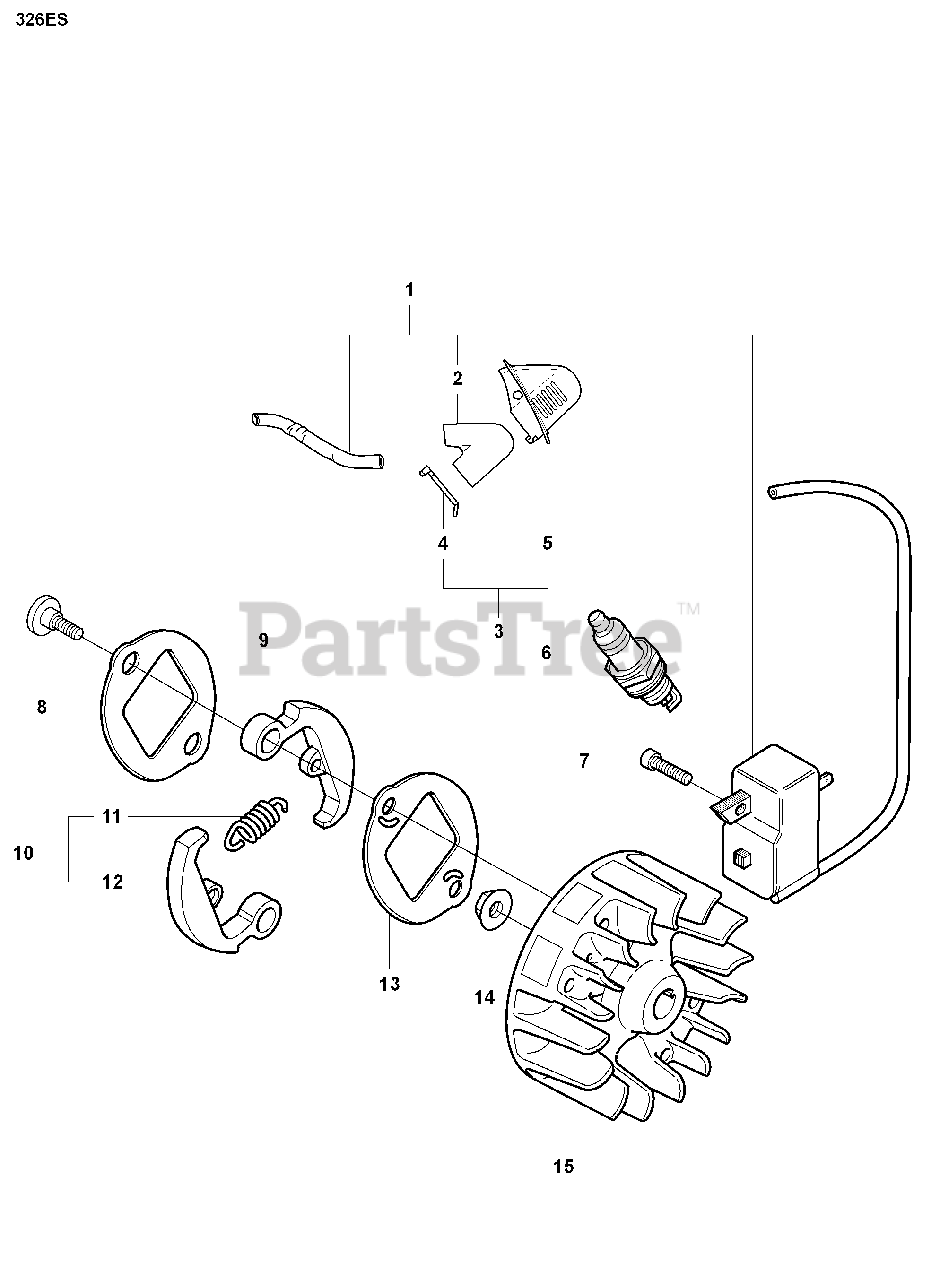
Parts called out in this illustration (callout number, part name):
1	IGNITION MODULE MB50
2	SPARK PLUG CONNECTION
6	Spark Plug, RCJ6Y
7	SCREW
9	WASHER, CLUTCH
14	FLANGE NUT
